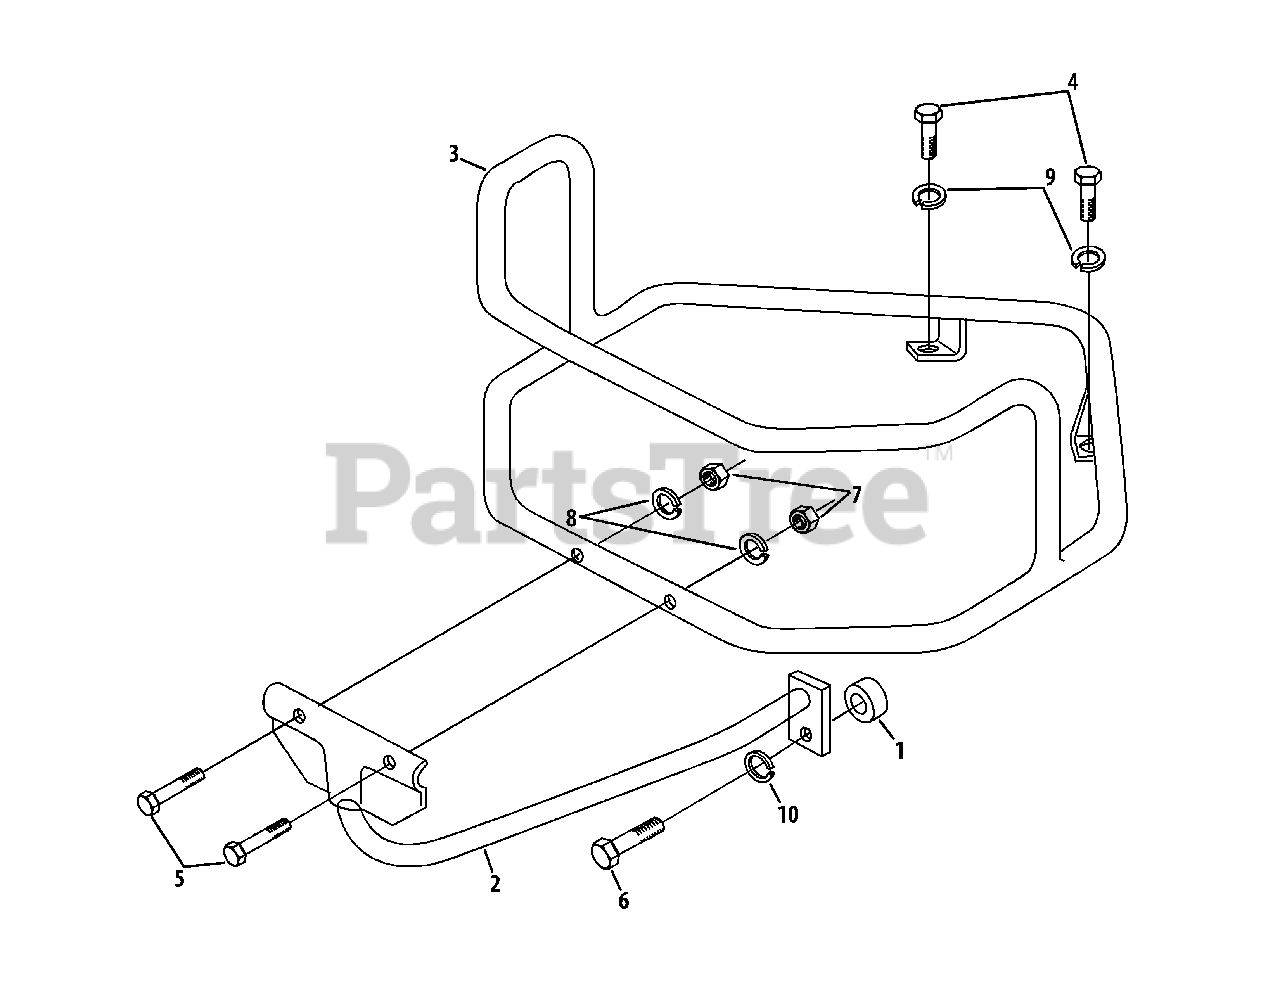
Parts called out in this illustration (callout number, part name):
1	Spacer, 1.0 x .546 x .5
2	Bottom Bumper Brace
3	Bumper Guard
4	Hex Screw, 3/8"-16 x 1.00
5	Hex Screw, 5/16"-18 x 1.50
6	Hex Screw, 1/2"-13 x 1.50
7	Hex Nut, 5/16"-18
8	Lock Washer, 5/16"
9	Lock Washer, 3/8"
10	Lock Washer, 1/2"
